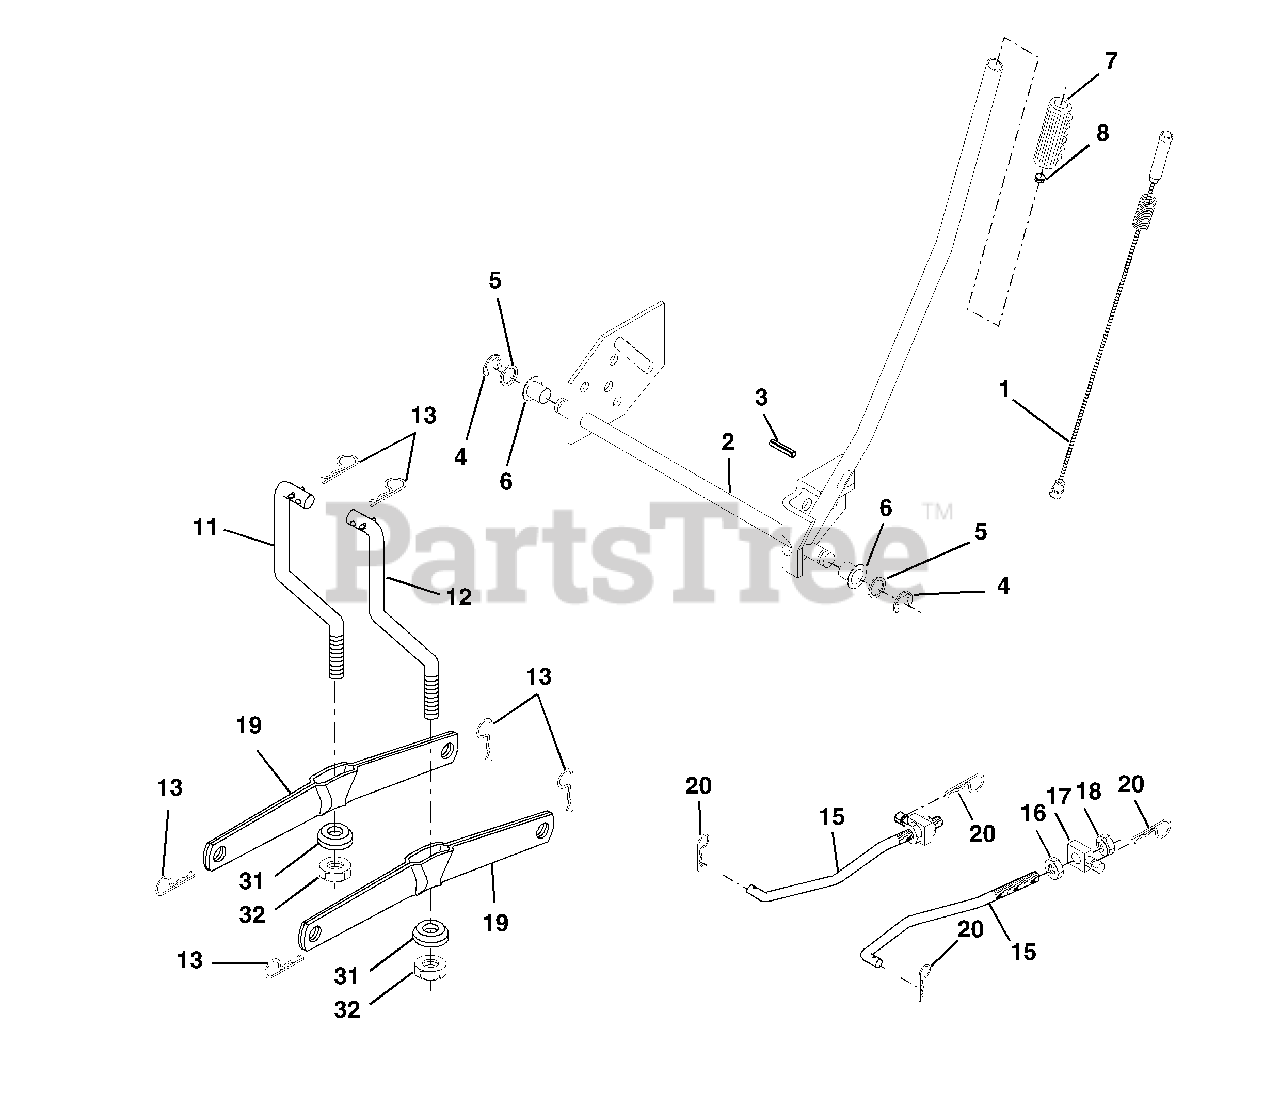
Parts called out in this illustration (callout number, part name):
1	Wire Asm Inner/Sprg w/Plunger
2	Shaft Asm Lift
3	Pin Groove
4	E Ring #5133-62
5	Washer 21/32 x 1 x 21 Ga.
6	Bearing Nylon
7	Grip Handle
8	Button Plunger
11	Link Lift Lh
12	Link Lift Rh
13	Retainer Spring
15	Link Front
16	Nut Jam Hex 1/2-13 Unc
17	Trunnion
18	Nut Lock w/Wsh 1/2-13 Unc
19	Arm Suspension Rear
20	Retainer Spring
31	Bearing Pvt Lift
32	Nut Crownlock 3/8-24
